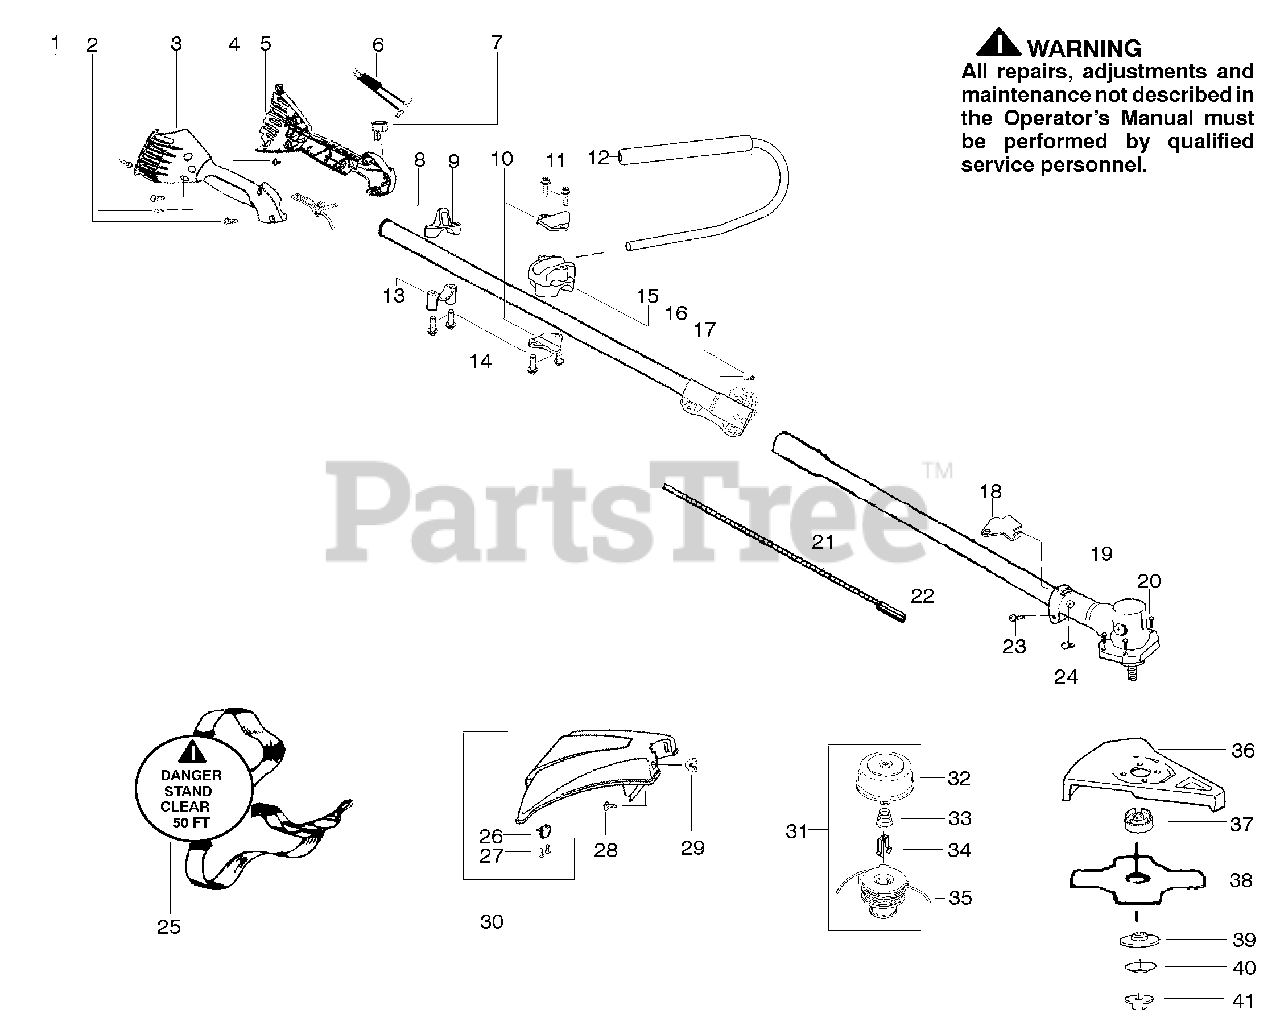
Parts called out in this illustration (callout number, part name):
1	Screw-alignment
3	Hsg.-Throttle-right
4	Screw-Cable Ret.
5	Hsg.-Throttle-left
8	Trigger-Throttle
9	Clamp-Harness (upper)
10	Clamp-Bracket
12	Assy.-Handlebar
13	Clamp-Harness (lower)
14	Screw
15	Clamp-Handlebar
16	Kit-Upper Shaft
18	Bracket-Shield
21	Shaft-Flex (lower)
22	Assy-Lower Shaft
25	Shoulder Strap
29	Wingnut
30	Kit-Shield Assy.
31	Accy-Cutting Head
32	Assy-Hub/Arbor
33	Spring-Return
34	Retainer-Spool
35	Accy-Wound Spool
36	Kit-Metal Shield
38	Accy.-Weed Blade
40	Washer-Belleville
